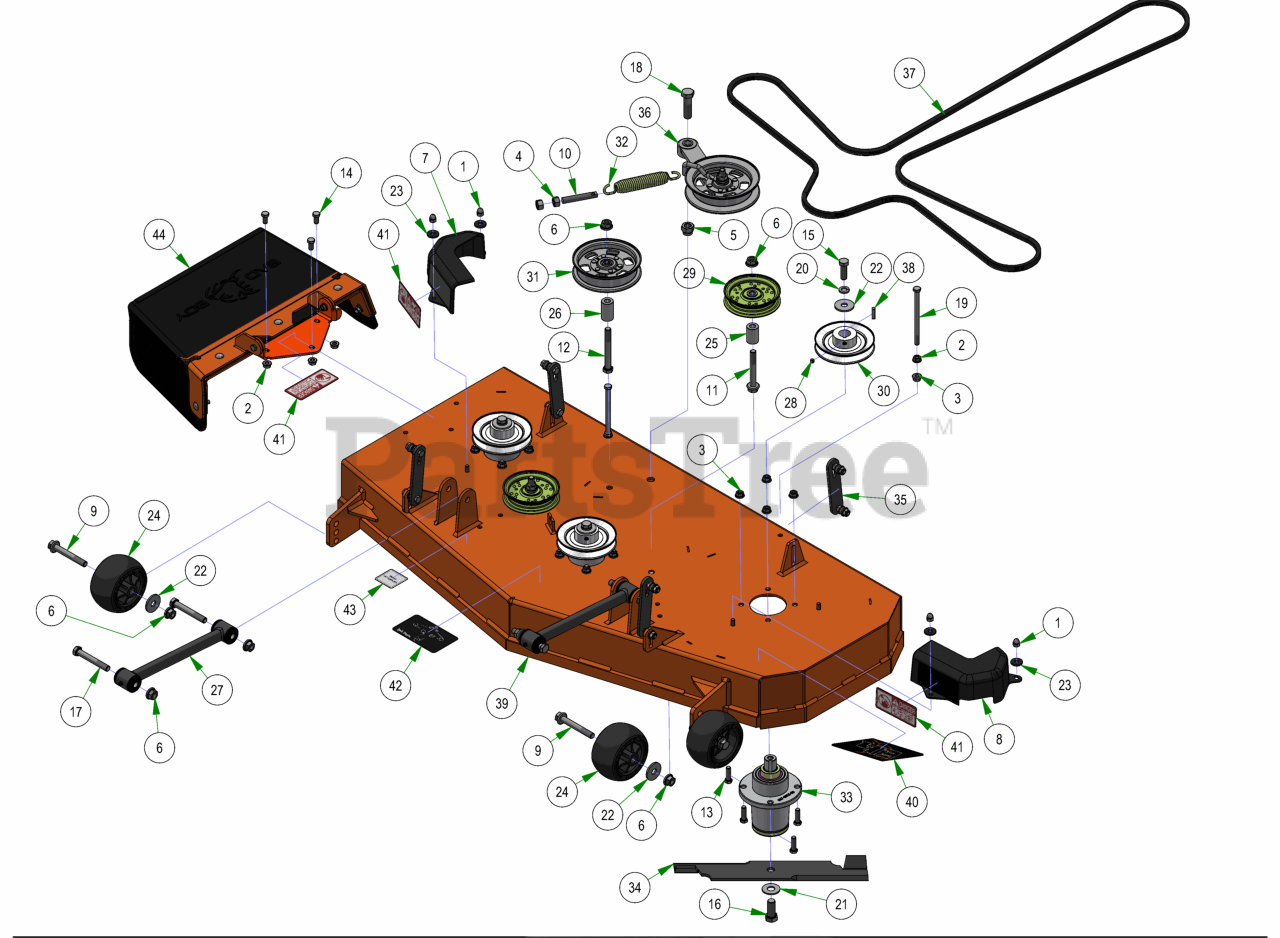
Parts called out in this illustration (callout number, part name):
1	5/16-18 ACORN NUT HIGH-CROWN ZC
2	3/8-16 HEX SERRATED FLANGE NUT HARD/ZINC
3	3/8-16 NYLON INSERT FLANGE LOCKNUT (GR.F) ZINC
4	1/2-13 HEX NUT ZINC
5	5/8-11 NYLON INSERT LOCKNUT ZINC
6	1/2-13 NYLON INSERT FLANGE LOCKNUT ZINC
7	Pulley Cover Chute Side
8	Pulley Cover Non-Chute Side
9	1/2-13 X 90MM HEX FLANGE BOLT W/SHOULDER (GR.8) ZINC
10	All Thread
11	1/2-13 X 3-1/2 HEX FLANGE BOLT (GR.8) ZINC
12	1/2-13 X 4 HEX CAP SCREW (GR.8) ZINC YELLOW
13	3/8-16 X 1-1/4 HEX CAP SCREW (GR.5) ZINC
14	3/8-16 X 3/4 HEX CAP SCREW (GR.5) ZINC
15	1/2-20 X 1-1/2 HEX CAP SCREW (GR.5) ZINC
16	5/8-18 X 1-1/2 HEX CAP SCREW (GR.8) ZINC YELLOW
17	1/2-13 X 3-1/2 HEX CAP SCREW (GR.5) ZINC
18	5/8-11 X 2-1/4 HEX CAP SCREW (GR.5) ZINC
19	3/8-16 X 5-1/2 HEX CAP SCREW (GR.5) ZINC
20	1/2 SPLIT LOCKWASHER (GR.8) ZINC/YELLOW
21	5/8 USS FLAT WASHER (1-3/4" OD) GR.8 ZINC YELLOW
22	1/2 BELLEVILLE WASHER (1-5/8 OD X .140 THK) ZINC
23	.360 ID X .983 OD X .120 THICK FLAT WASHER NYLON BLACK
24	Deck Wheel
25	.502 ID X .750 OD X 1.500 Long Spacer
26	1 3/4" Pulley Spacer
27	Hybrid Turnbuckle/Deck Locator
28	5/16-24 X 1/4 SOCKET SET SCREW (CUP PT) PLAIN
29	4 3/4 Idler Pulley - ABFI-76
30	5" Spindle Deck Pulley
31	5-3/4 Idler Pulley
32	Deck Idler Spring
33	Spindle Assembly
34	48" ZT/Mav/Compact Outlaw Blade with Fusion
35	Deck Hanger Assembly
36	Maverick HD & Down Deck Idler Assembly
37	B147 Deck Belt
38	1/4 X 1 SQ MACHINERY KEY 1018 STL PLN
39	2025 48" x 5" Deck
40	48" Grip Deck Decal
41	Danger Decal-Spindle/Discharge
42	Deck Belt Route Decal
43	Deck Impact Patent Decal 9591803
44	ZT Chute Assembly
